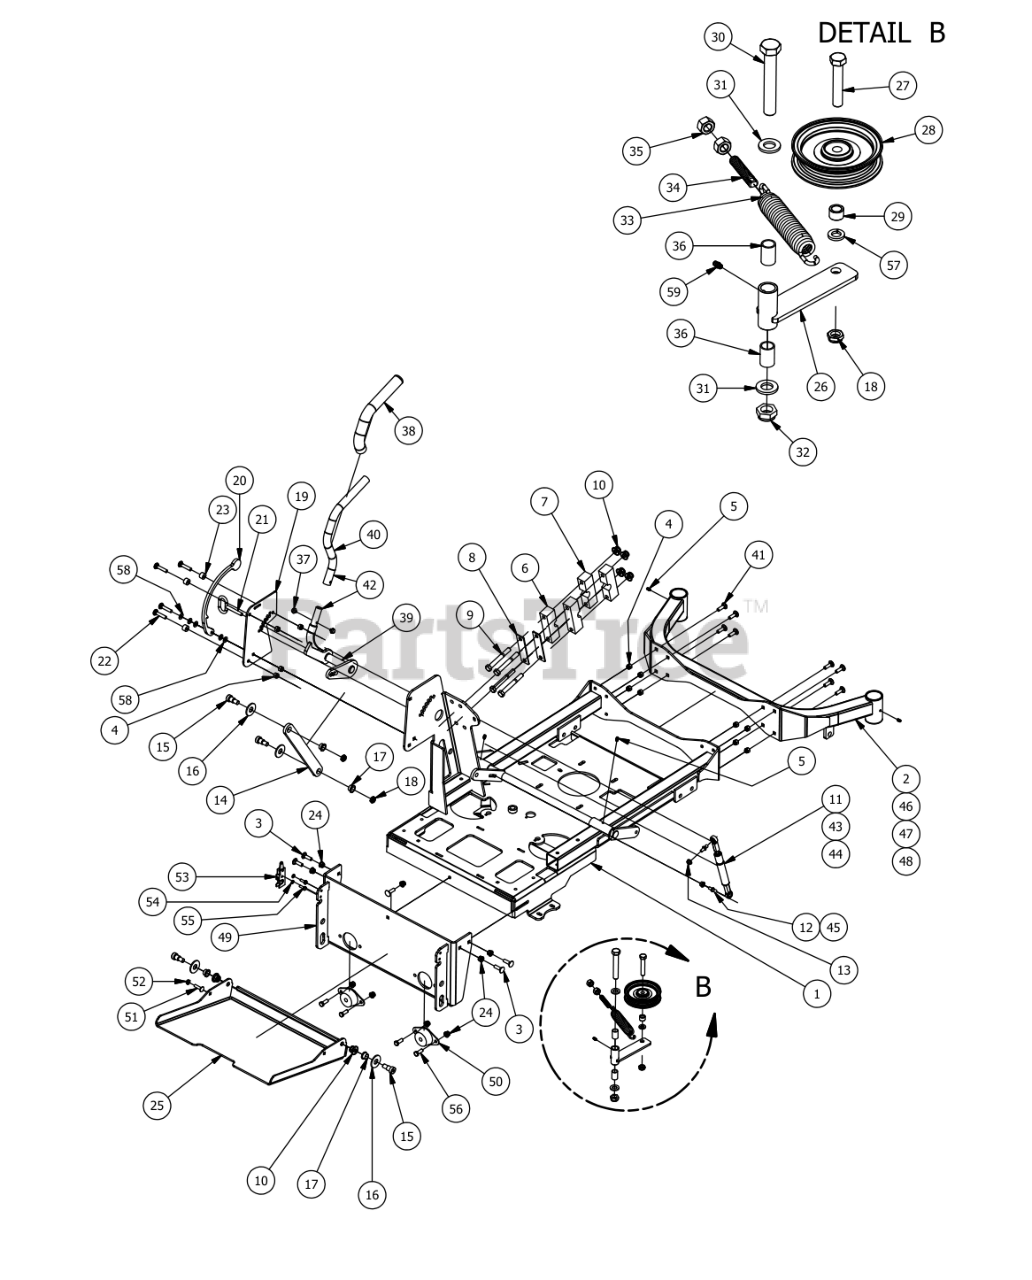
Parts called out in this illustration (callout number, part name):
1	2015 Stand-On Frame
2	48" Front End (2015 Stand-On)
3	3/8" x 1 1/4" Carriage Bolt
4	3/8 Nylock Nut
5	1/4" Press in Grease Fitting
6	Two Piece Pillow Block (Male)
7	Two Piece Pillow Block (Female)
8	Two Piece Pillow Block Strap
9	1/2" x 4" Bolt (Grade 8)
10	1/2-13 Nylon Flange Nut
11	200 lb Gas Spring- 48" Deck
12	10mm Damper Ball Stud-Steering
13	5/16" Flange Nut
14	Stand On Flat Linkage Bar
15	5/8" x 5/8" Shoulder Bolt
16	5/8" Flat Washer
17	Bronze Bushing - SF - 2024-8
18	1/2" Nylcock Nut (1/2 Jam)
19	2015 Stand-On Adjustment Plate (Bolt On)
20	2015 Stand-On Deck Lever Lock
21	Pin And Lanyard
22	3/8 x 1 3/4 Carriage Bolt
23	ACS Spacer 3/4x3/8x1/2
24	3/8" Nylock Flange Nut
25	2016 Stand-On Platform
26	Stand-On Pump Idler Bracket
27	1/2" x 2 3/4" Hex Bolt
28	4 3/4" Idler Pulley
29	1/2 x 1/2 Spacer
30	5/8" x 4" Hex Bolt
31	.630 ID Plastic Washer
32	5/8" Nylock (1/2 Jam)
33	2009 Deck/Pump Idler Spring
34	All Thread-Pump Idler Tensioner
35	1/2" Hex Nut
36	Idler Retainer bushing
37	5/16-18 1/2 HWH Bolt-Steering
38	rubber grip
39	Stand-On Deck Lift Lever
40	Stand-On Deck Lift Handle
41	3/8"-16 x 1 1/4" Carriage Bolt
42	Deck Lift Lever Assembly uses parts: 37, 38, 39, & 40
43	250 lb Gas Spring- 54" Deck
44	300 lb Gas Spring-61" Deck
45	13 mm Damper Ball Stud
46	54" Front End (2015 Stand-On)
47	61" Front End (2015 Stand-On)
48	36" Front End (2016 Stand-On)
49	Stand-On Platform Support
50	Rubber Isolator
51	5/16" x 1 1/4" Carriage Bolt
52	5/16-18 Nylock Jam Nut 1/2 Nut
53	Latch-Stand On
54	1/4" Lock Washer
55	1/4" x 3/4" Hex Bolt
56	3/8" x 1" Hex Bolt
57	1/2" Lock Washer
58	.390 x .750 x .062 Nylon Washer
59	1/4" Press in Grease Fitting
